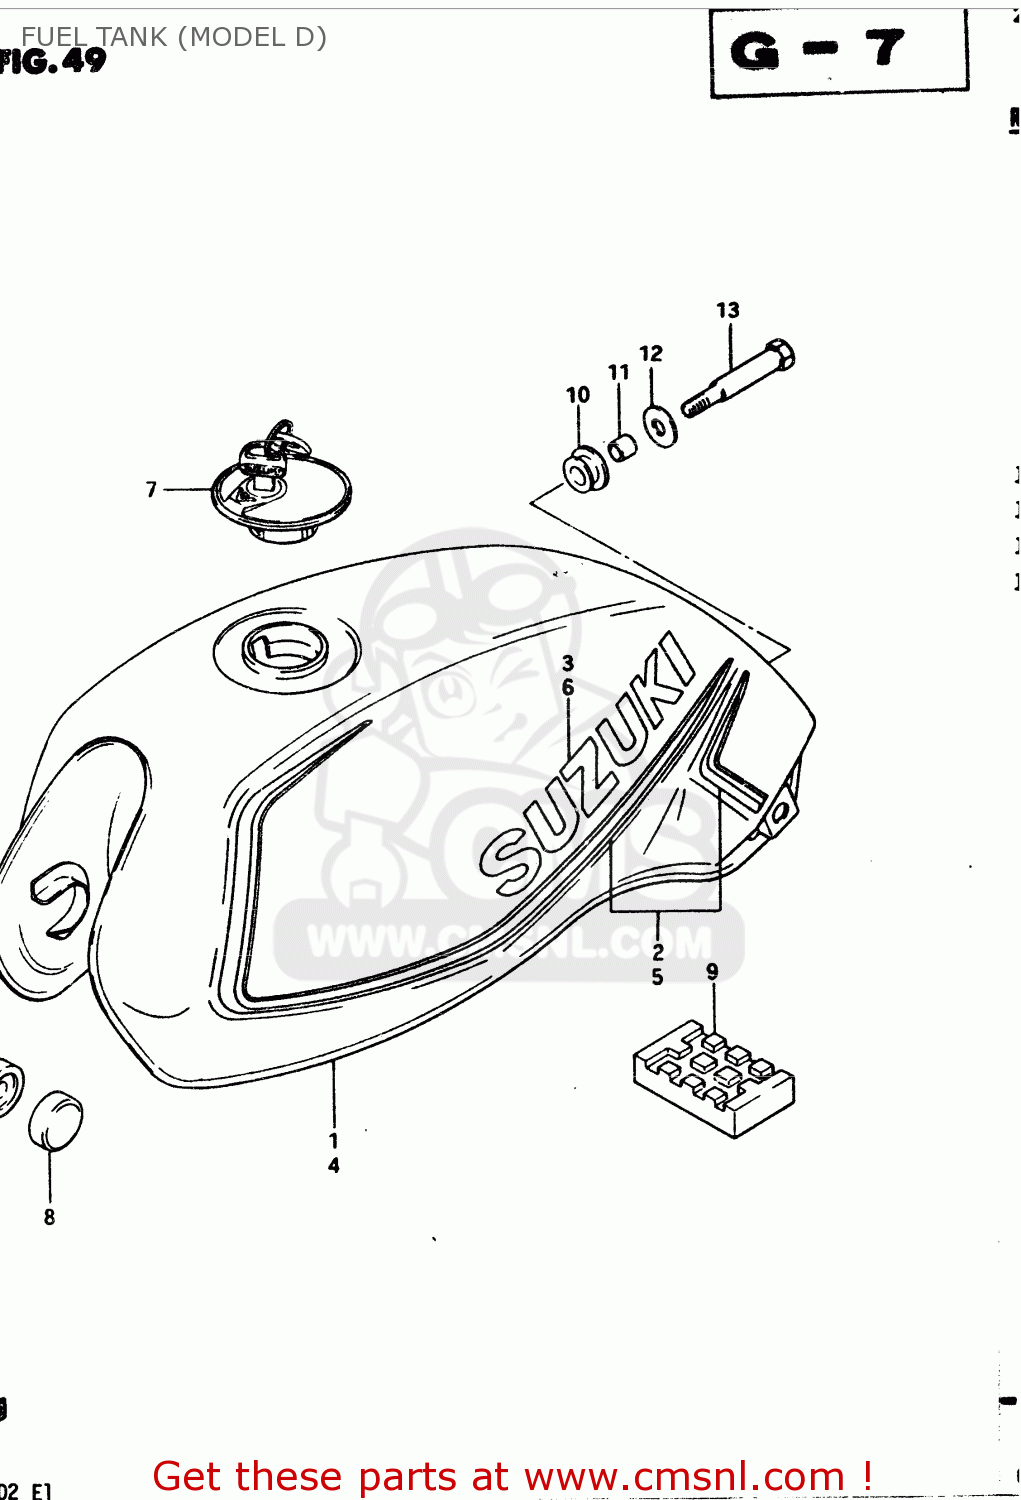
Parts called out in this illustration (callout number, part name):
1	TANK SET, FUEL (RED)
2	TAPE SET, FUEL TANK
3	EMBLEM(SILVER)
4	TANK SET, FUEL (SILVER)
5	TAPE SET, FUEL TANK
6	EMBLEM(ORANGE)
7	CAP SET,FUEL TANK
8	CUSHION
9	CUSHION,FUEL TANK CTR
10	CUSHION
11	SPACER (6.8X10X10)
12	WASHER (6.5X29X1.6)
13	BOLT(6X60)
